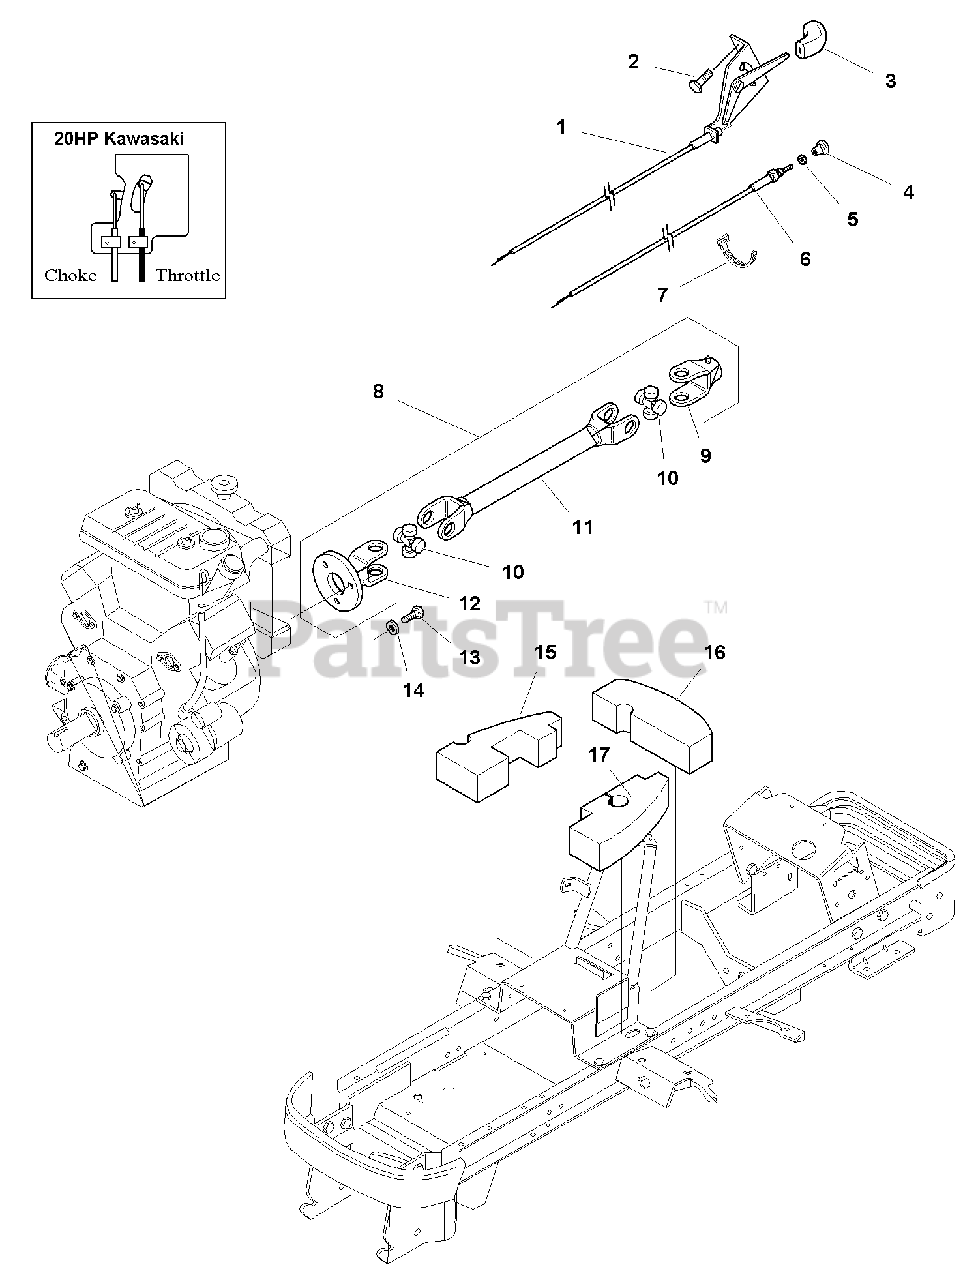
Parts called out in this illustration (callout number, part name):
1	CONTROL, Throttle
2	CAPSCREW, Plastite
3	KNOB, Throttle
4	KNOB, Choke
5	NUT, Hex, #10-24
6	CONTROL, Choke
8	DRIVE SHAFT ASSEMBLY (Includes Ref. Nos. 9-12 )
10	CROSS & BEARING KIT
11	YOKE & TUBE ASSEMBLY
12	YOKE & FLANGE ASSEMBLY
13	SCREW, Socket Head, M8 x 1.25 x 50mm
14	LOCKWASHER, Internal Tooth
15	SEAL, RH Tunnel
16	SEAL, Rear Tunnel
17	SEAL, LH Tunnel
